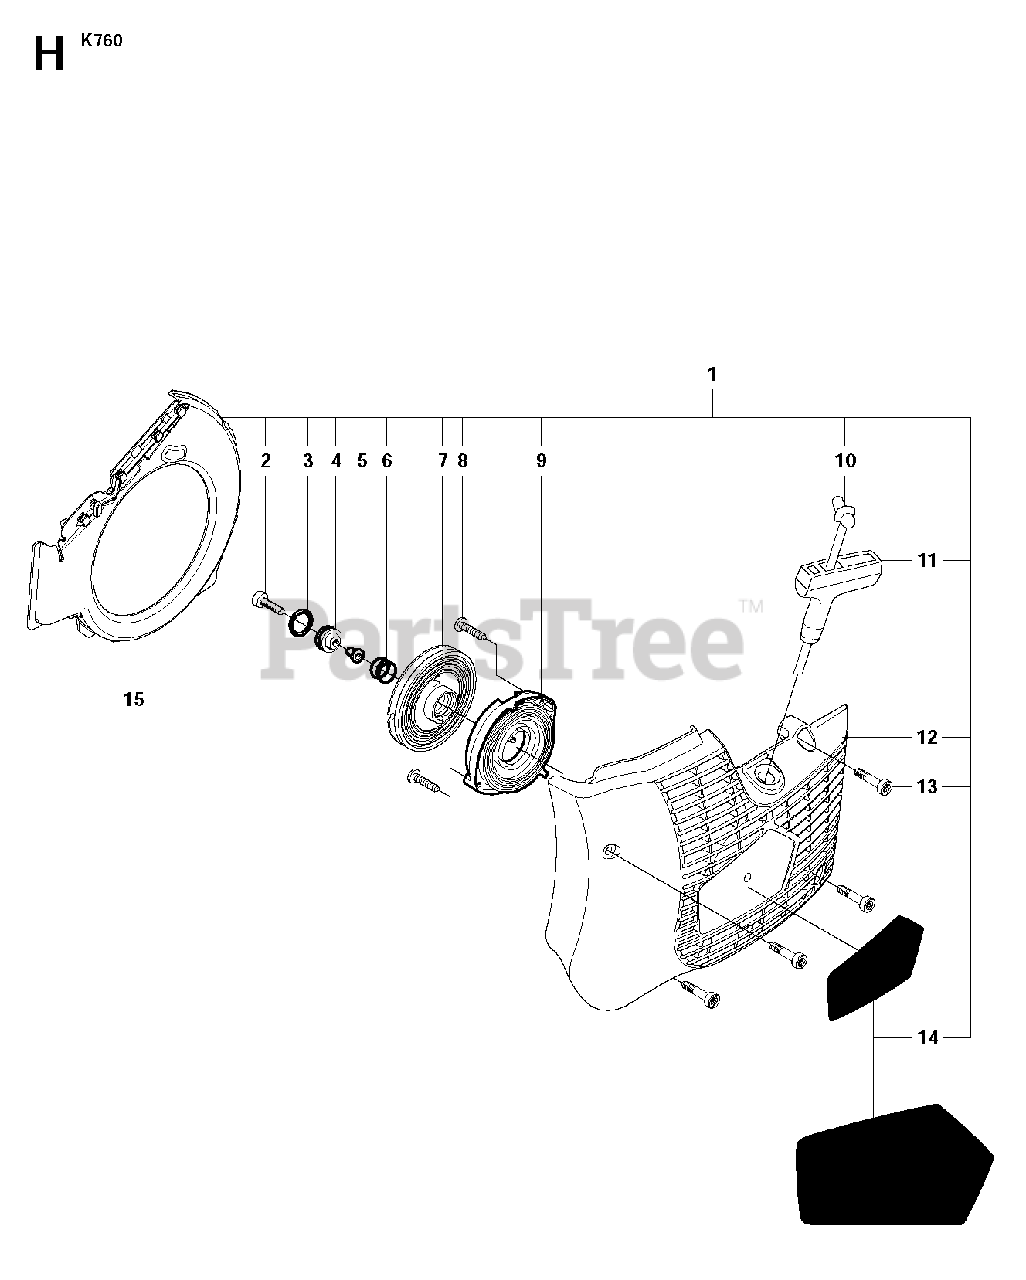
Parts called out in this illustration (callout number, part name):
1	STARTERIncl. 2 - 15
2	SCREW ITXSCT
5	SPACING SLEEVE
6	COMPRESSION SPRING
7	STARTER PULLEY
8	SCREW CCRPANT
9	RECOIL SPRING
10	STARTER CORD50 m
11	STARTER HANDLE
12	STARTER COVER
13	SCREW ITXSCM
15	AIR CONDUCTOR
